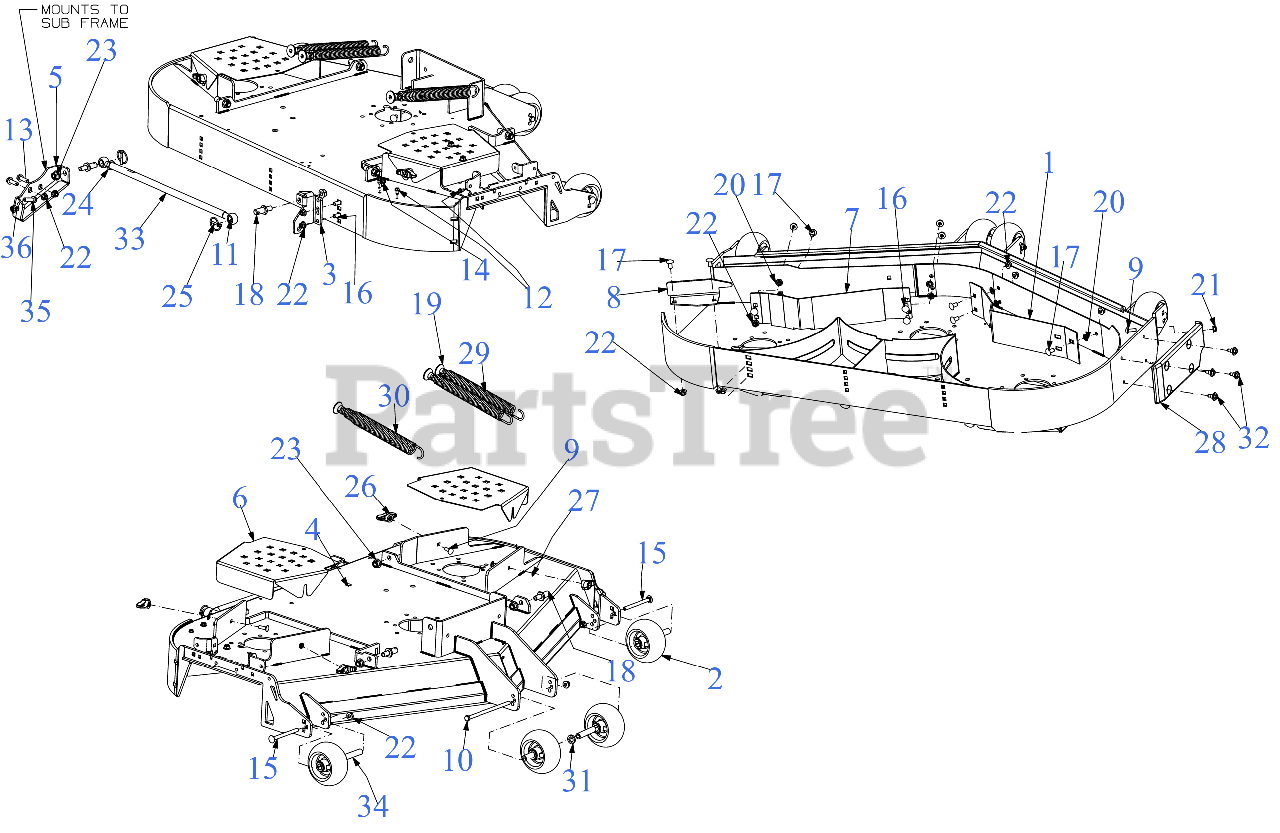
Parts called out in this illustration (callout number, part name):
1	BAFFLE - 54" ADJ
2	5" DIA DECK WHEEL COMPLETE
2	WHEEL BUSHING
5	STABILIZER MOUNTING BRACKET
8	DECK CHUTE BAFFLE
9	CARRIAGE BOLT 5/16-18 x 1.00
10	SCREW 3/8-16 x 7.25 GR5
11	BOLT 5/8-16 x 2.63
12	SCREW 1/4-20 X.500
13	SCREW 3/8-16 x 1.25 GR5
14	SCREW 5/16-18 x .500
15	CARRIAGE BOLT 3/8-16 x 4.25 GR5
16	CARRIAGE BOLT 3/8-16 x 1.00 GR5
17	CARRIAGE BOLT 3/8-16 x .75
19	SPRING INSERT SCREW
21	FLANGE LOCK NUT 5/16-18
24	HEX JAM NUT
25	LYNCH PIN .1875
26	WING KNOB 5/16-18
28	DECK SKID PLATE (LH)
29	EXTENTION SPRING 1.20 x 11.35
30	EXTENSION SPRING 1.44 OD x 11.36
31	FLAT WASHER .632X1.00X.16
32	SHOULDER SCREW .43X.29X5/16-18 TT
34	WHEEL SPACER .38ID x 3.04LG
35	HEX HEAD BOLT (3/8-16:1.50 GR8)
36	LOCK NUT (3/8-16)
